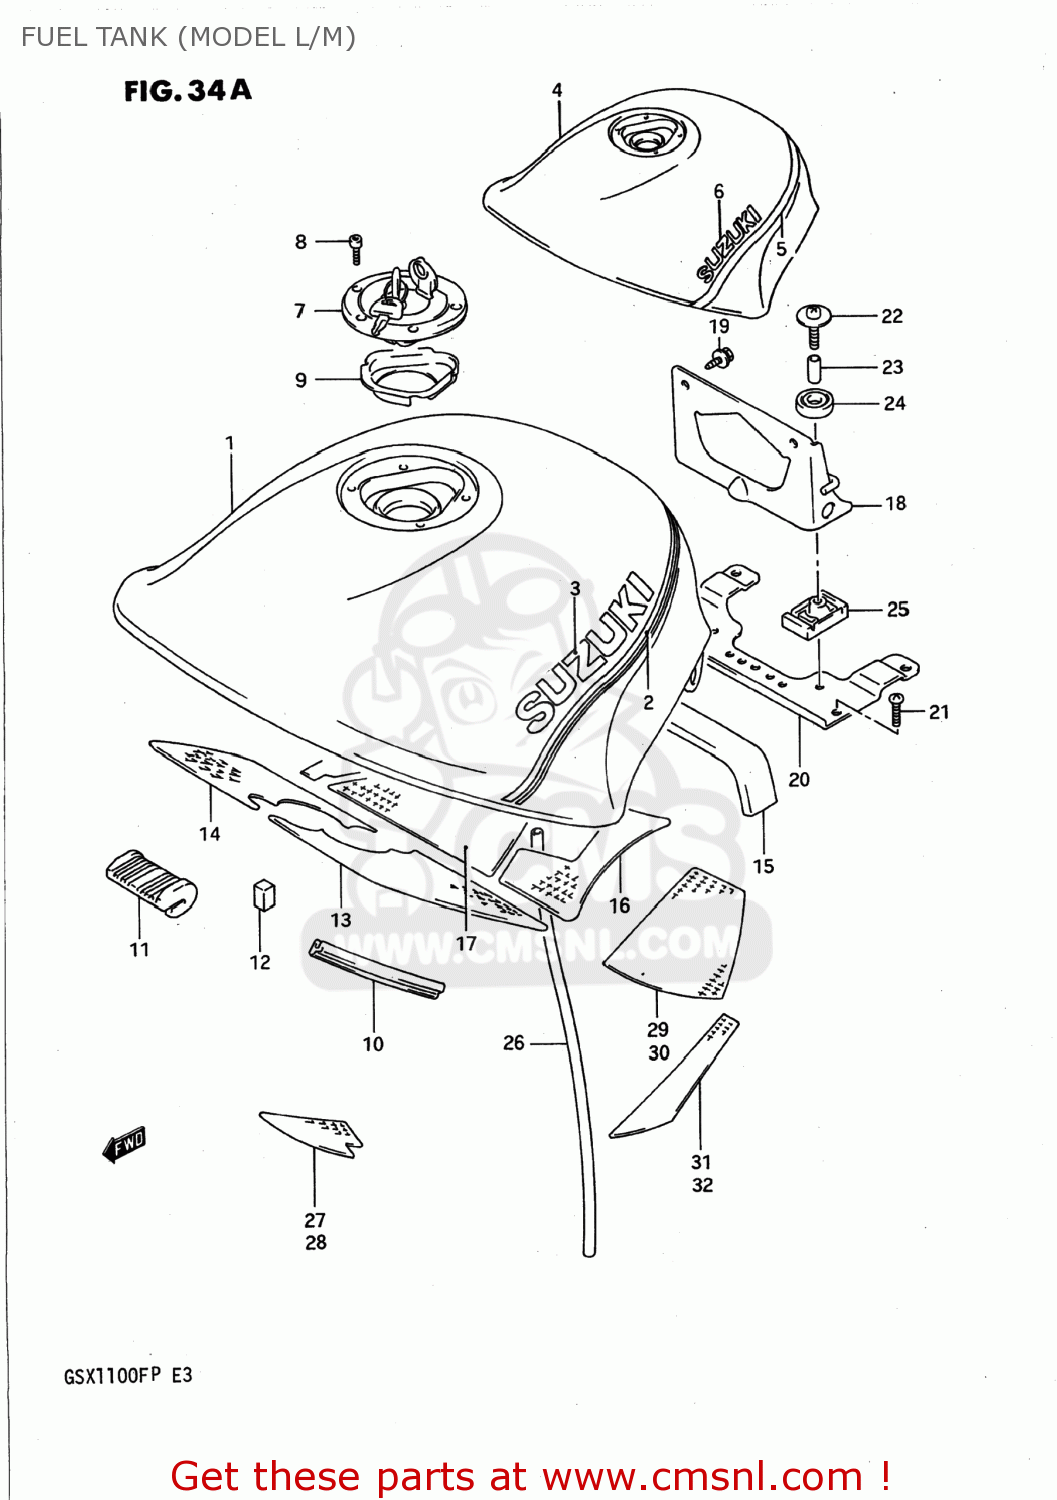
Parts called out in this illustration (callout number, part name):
1	TANK ASSEMBLY,FUEL
2	TAPE,FUEL TANK
3	EMBLEM
4	TANK ASSEMBLY,FUEL
5	TAPE,FUEL TANK STRIPE
6	EMBLEM (SUZUKI)
7	CAP SET,FUEL TANK
8	BOLT(5X10)
9	COVER,FUEL TANK INLET
10	MOLDING,FUEL TANK
11	CUSHION,FUEL TANK FR
12	CUSHION,FUEL TANK SIDE
13	HEATSHIELD,FUEL TANK FR,L
14	HEAT SHIELD,FUEL TANK
15	HEAT SHIELD,FUEL TANK
16	HEATSHIELD,FUEL TANK RR,L
17	HEAT SHIELD,FUEL TANK
18	BRACKET COMP,FUEL TANK
19	SCREW(6X16)
20	BRACKET,FUEL TANK RR LOW
21	SCREW, CENTER
22	BOLT L:35,WITH WASHER
23	SPACER (6.4X9X21.5)
24	CUSHION
25	CUSHION
26	HOSE (7X10.2X1000)
27	HEAT SHIELD,FUEL TANK
28	HEAT SHIELD,FUEL TANK
29	HEAT SHIELD,FUEL TANK
30	HEAT SHIELD,FUEL TANK
31	HEAT SHIELD,FUEL TANK
32	HEAT SHIELD,FUEL TANK
